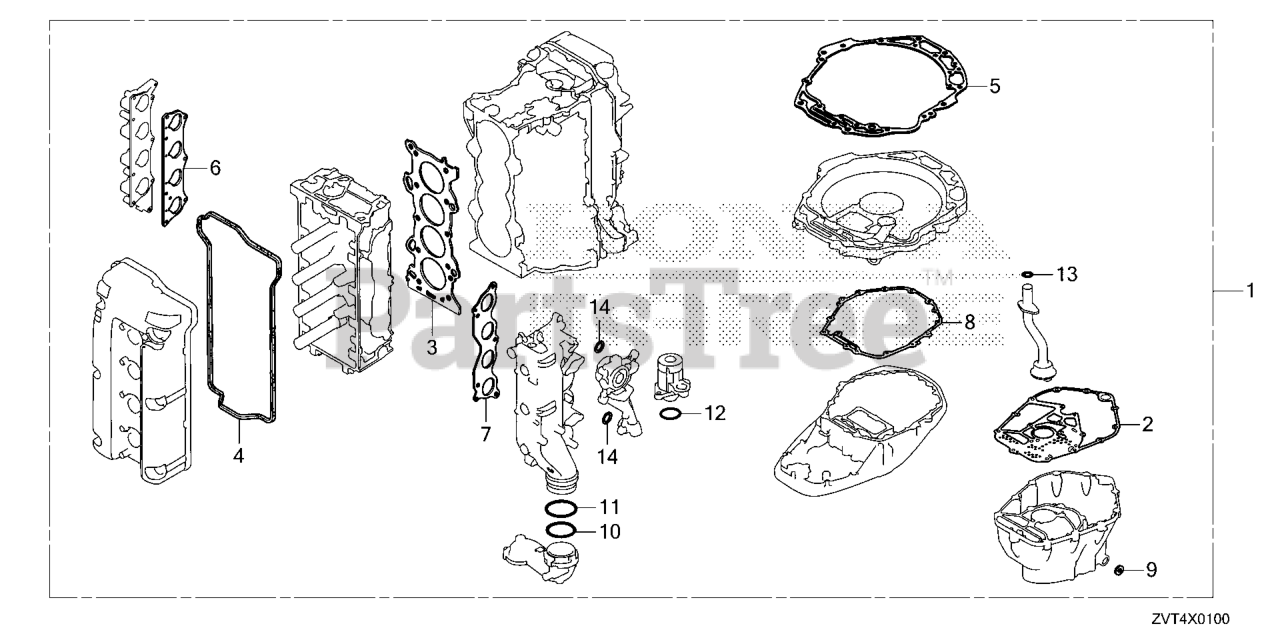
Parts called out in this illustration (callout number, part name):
1	GASKET KIT
2	GASKET, OIL PAN
3	GASKET, CYLINDER HEAD
4	GASKET, CYLINDER HEAD COVER
5	GASKET, OIL PUMP BODY
6	GASKET A, INJECTOR BASE
7	GASKET, EX. MANIFOLD
8	GASKET, MOUNT CASE
9	WASHER, DRAIN PLUG (12MM)
10	O-RING (76.4X3.1)
11	O-RING (79.8X3.1)
12	O-RING (59.4X3.1)
13	O-RING (20.6X2.6)
14	O-RING (22.5X2.4)
